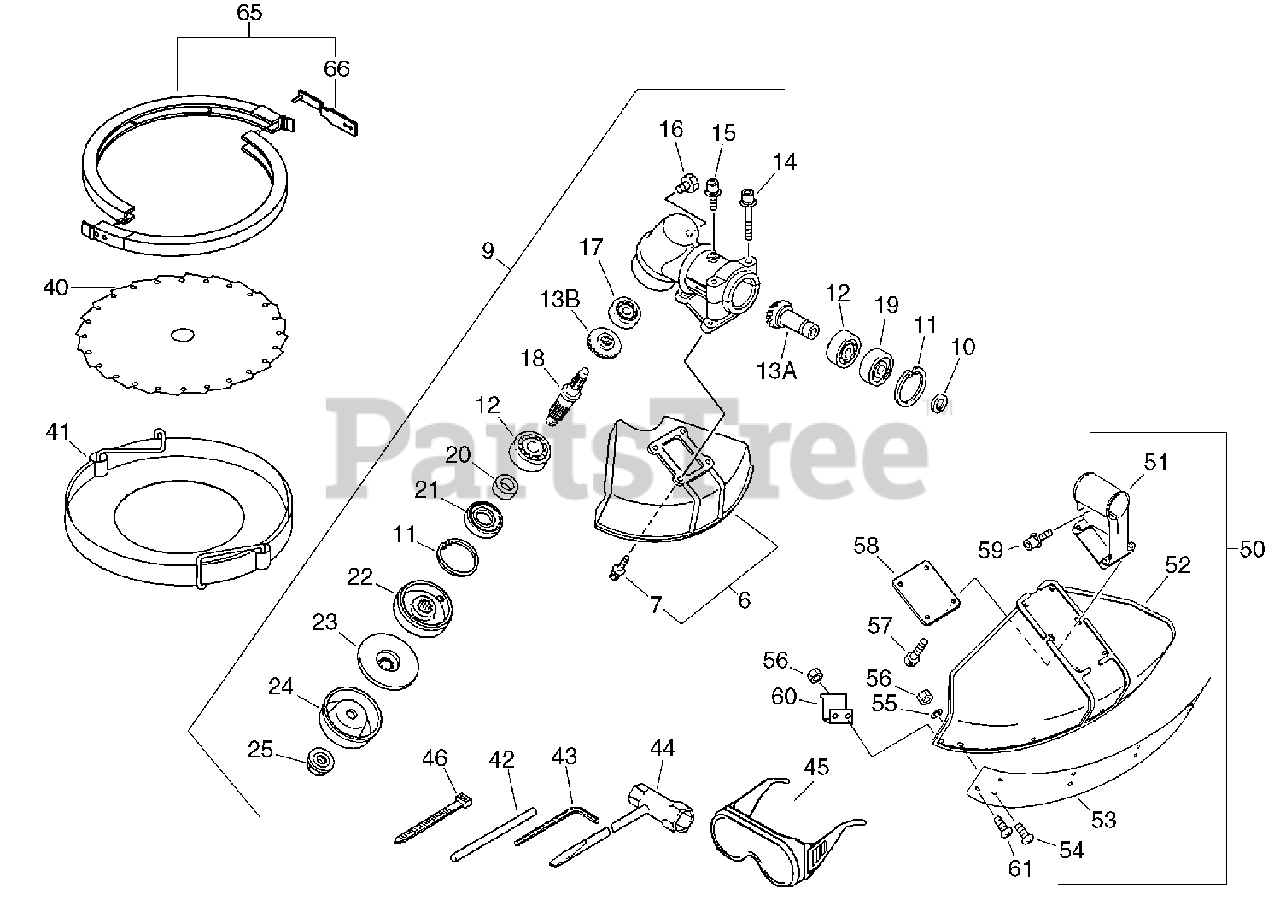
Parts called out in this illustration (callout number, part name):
9	GEAR CASE ASSY
10	RING, RETAINING - 15
11	RING, RETAINING - 35
12	BEARING, BALL - 6202
13	GEAR SET
14	SCREW - 5X35
15	SCREW - 5X14
16	BOLT - 8X8
17	BEARING, BALL - 6001
18	GEAR - SHAFT
19	BEARING, BALL - 6202Z
20	SPACER, OILSEAL
21	SEAL, OIL
22	ADAPTOR, BLADE - UPPER
23	ADAPTOR, BLADE - LOWER
24	PLATE, CUP
42	LOCKING TOOL
43	HEX KEY - 4mm
44	T-WRENCH - 17X19mm
45	GOGGLES
46	TIE, CABLE - SMALL
50	DEBRIS SHIELD KIT
51	BRACKET, SHIELD
52	SHIELD, DEBRIS
53	GUARD, SHIELD
54	SCREW - 5X18
55	WASHER - 5
57	SCREW - 5X14
58	BRACKET, SHIELD
59	SCREW - 5X25
60	KNIFE, TRIMMER LINE
61	SCREW - 5X12
65	COVER, BLADE
